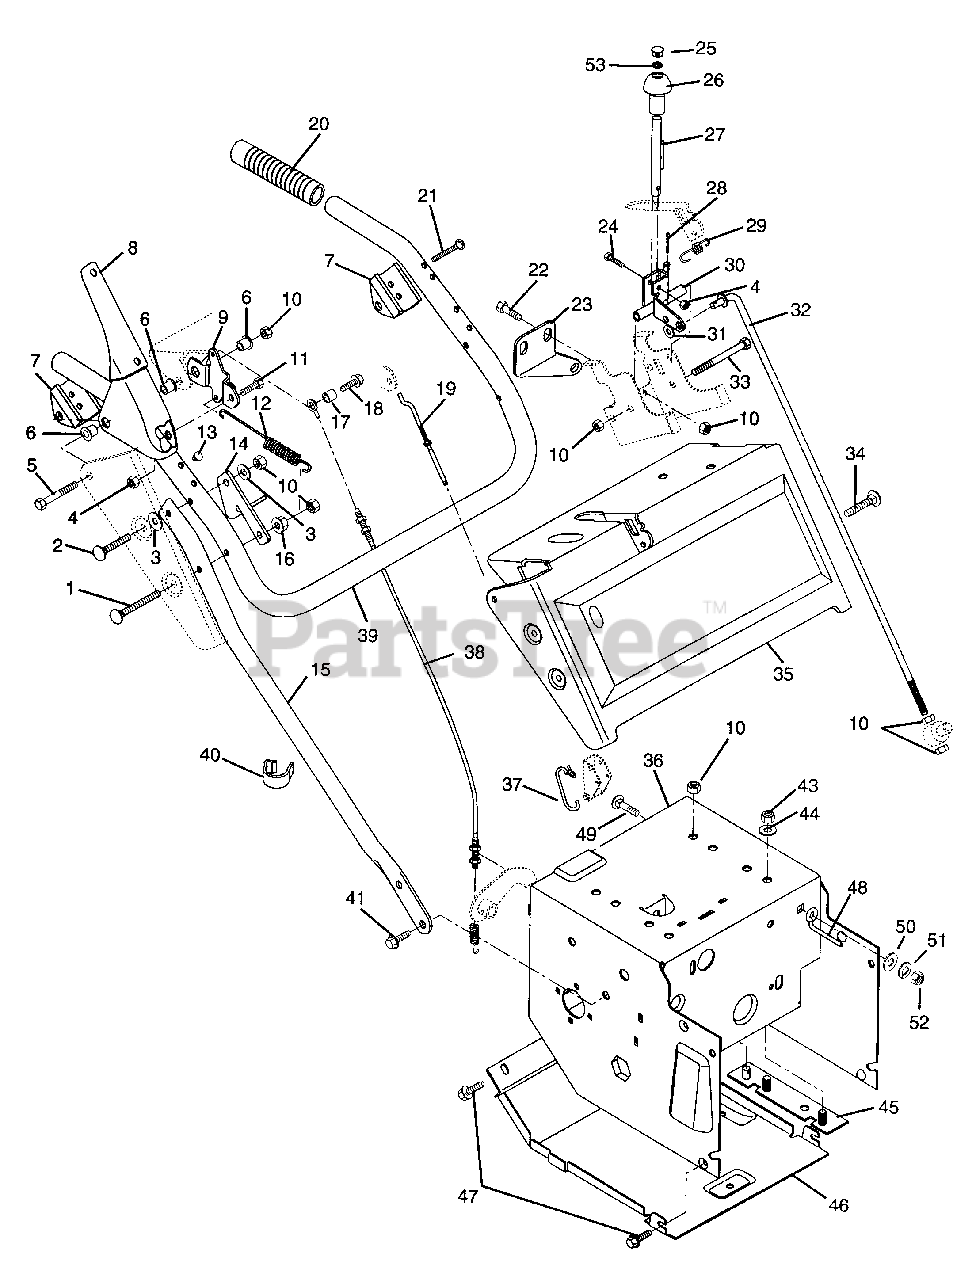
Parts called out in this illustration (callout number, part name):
1	BLT-RDHDSQSHNK.31-18X2.75G2YWZ
2	@BLT-RDHDSQNK .31-18X1.50 G5YZ
3	@WSHR-FL-STL.438X1.00X.083 YWZ
4	@NUT-LK-CTR .25-20 YWZC
5	@BLT-HEX .31-18X2.50 GR5 YWZC
6	BSHG-FLG .325X.465X.333X.685
7	HANDLE PIVOT
8	CLUTCH LEVER - COATED
10	@NUT-LK-CTR .31-18 YWZC
11	BLT-HEX .25-20X.38 YWZC GR5
12	SG-TENS .051X.50X5.12 WLD 10.4
14	UPPER CABLE ANCHOR R H
15	L H LOWER HANDLEBAR
16	@NUT-SPNLK-FLG .312-18 YWZC
17	SPACER .230X.310X.255
18	@SCR-TAP 12-24X.50 HWH TR YWZC
19	CABLE, ADJUSTABLE
20	HANDLE GRIP
21	SCR-TAP 12-24X1.50 CROVH YZ BT
22	@BLT-HEX .31-18X.50 GR5 YWZC
23	CHUTE CRANK BRACKET
24	@BLT-HEX .25-20X1.00 GR5 YWZC
25	HOLE PLUG
27	ROD
28	@PIN-CTR .09X.75 EXTPRSQCT YWZ
29	SG-TENS .055X.33X1.31 WLD 7
31	WSHR-FL-STL .323X.625X.062 YWZ
32	SHIFT ROD
33	@BLT-HEX .31-18X3.50 GR5 YWZC
34	BLT-RDHDSQSHK .31-18X1.75 YWZC
35	PANEL W/DECAL
38	CLUTCH CABLE-ATTACHMENT
39	UPPER HANDLEBAR
40	CLUTCH FORK
41	BLT-SERHFWH .312-18X.625 YWZC
43	@NUT-HEX .31-18 YWZC
44	WSHR-LK .312X.097 PL HVY
45	ENGINE MOUNT, 5L,7L,8R
46	COVER BOTTOM
47	@SCR-TAP .25-20X.37 HWH YWZ TR
48	BELT FINGER LOWER
49	@BLT-RDHDSQNK .31-18X1.00 G5YZ
50	@WSHR-FL-STL.38X.875X.083 YWZC
51	@WSHR-LK .31X.078 REG YWZC
52	@NUT-HEX .31-18 YWZC
53	RG-RTNG-EXT .500X.015
